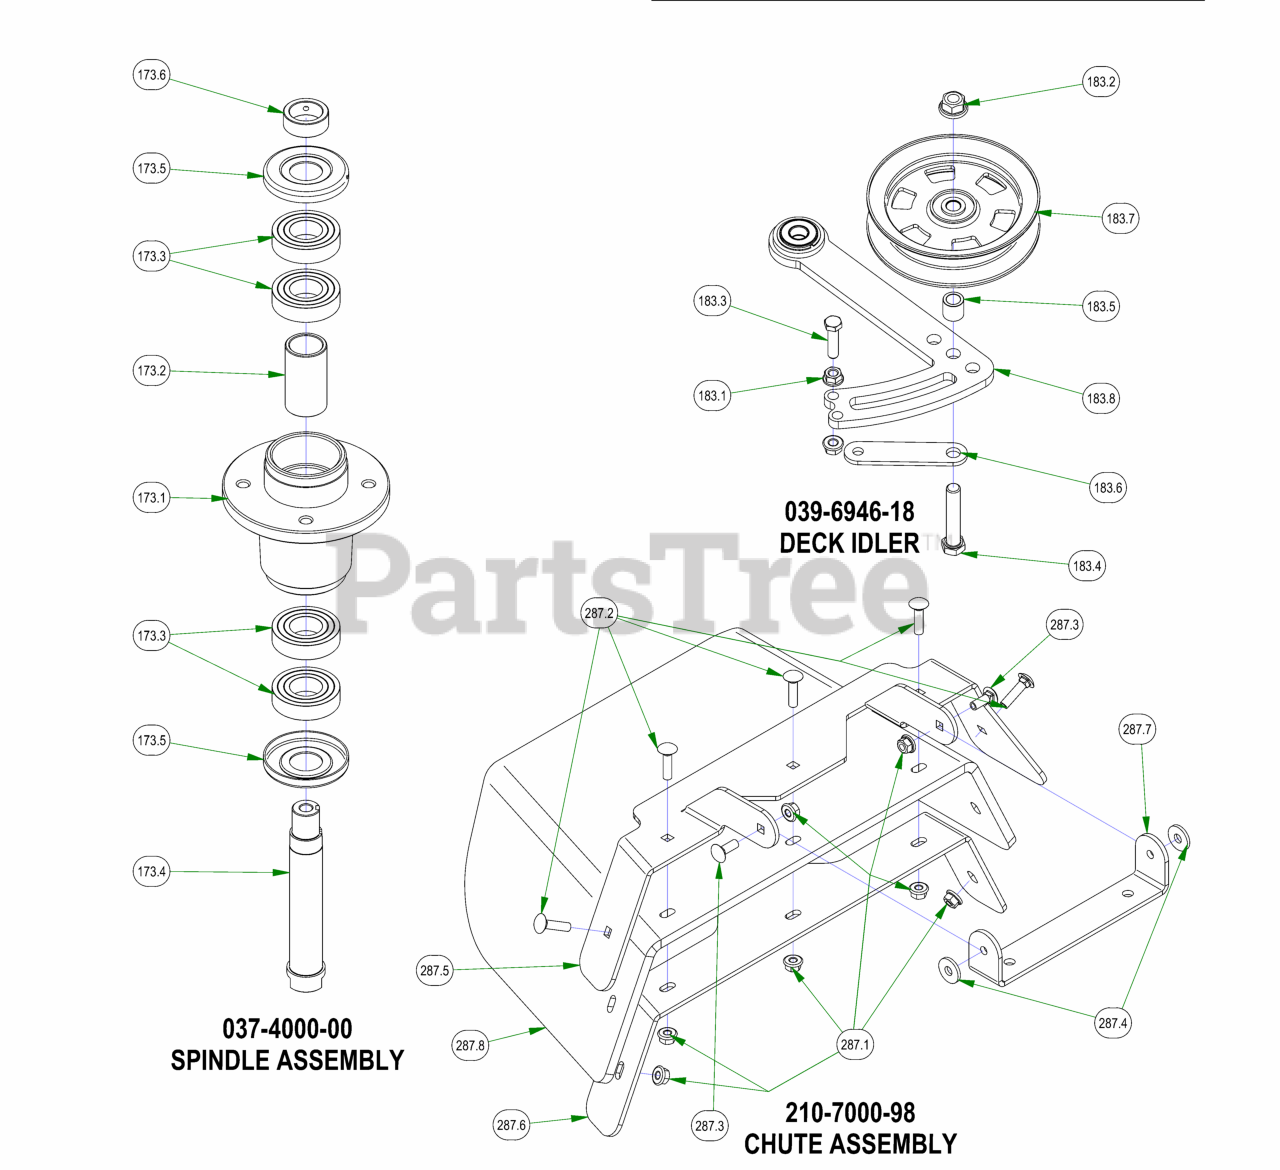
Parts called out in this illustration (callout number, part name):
173	OUTLAW SPINDLE ASSEMBLY
173.1	4000 Series Spindle Housing
173.2	4000 Series Spindle Spacer
173.3	Bearing - 6206
173.4	Spindle Shaft
173.5	Spindle Dust Cap
173.6	Locking Collar w/ 1/4"-20 Set Screw
183	2019 Rebel Rogue Deck Idler
183.1	3/8-16 HEX SERRATED FLANGE NUT HARD/ZINC
183.2	1/2-13 NYLON INSERT FLANGE LOCKNUT ZINC
183.3	3/8-16 X 1-1/2 HEX CAP SCREW (GR.5) ZINC
183.4	1/2-13 X 2-3/4 HEX CAP SCREW (GR.5) ZINC
183.5	.51 ID X .75 OD X .75 LGTH SOLID SPACER ZINC
183.6	Belt Tensioner Retainer Plate
183.7	5" Idler Pully
183.8	2019 Deck Tensioner
287	2019 Outlaw Gen2 Chute Assembly
287.1	5/16-18 NYLON INSERT FLANGE LOCKNUT ZINC
287.2	5/16-18 X 1-1/4 CARRIAGE BOLT ZINC
287.3	5/16-18 X 7/8 CARRIAGE BOLT ZINC
287.4	.360 ID X .983 OD X .120 THICK FLAT WASHER NYLON
287.5	2019 Upper Chute Bracket
287.6	2019 Lower Chute Bracket
287.7	2019 Chute Hanger
287.8	2019 Belted Chute with Logo
